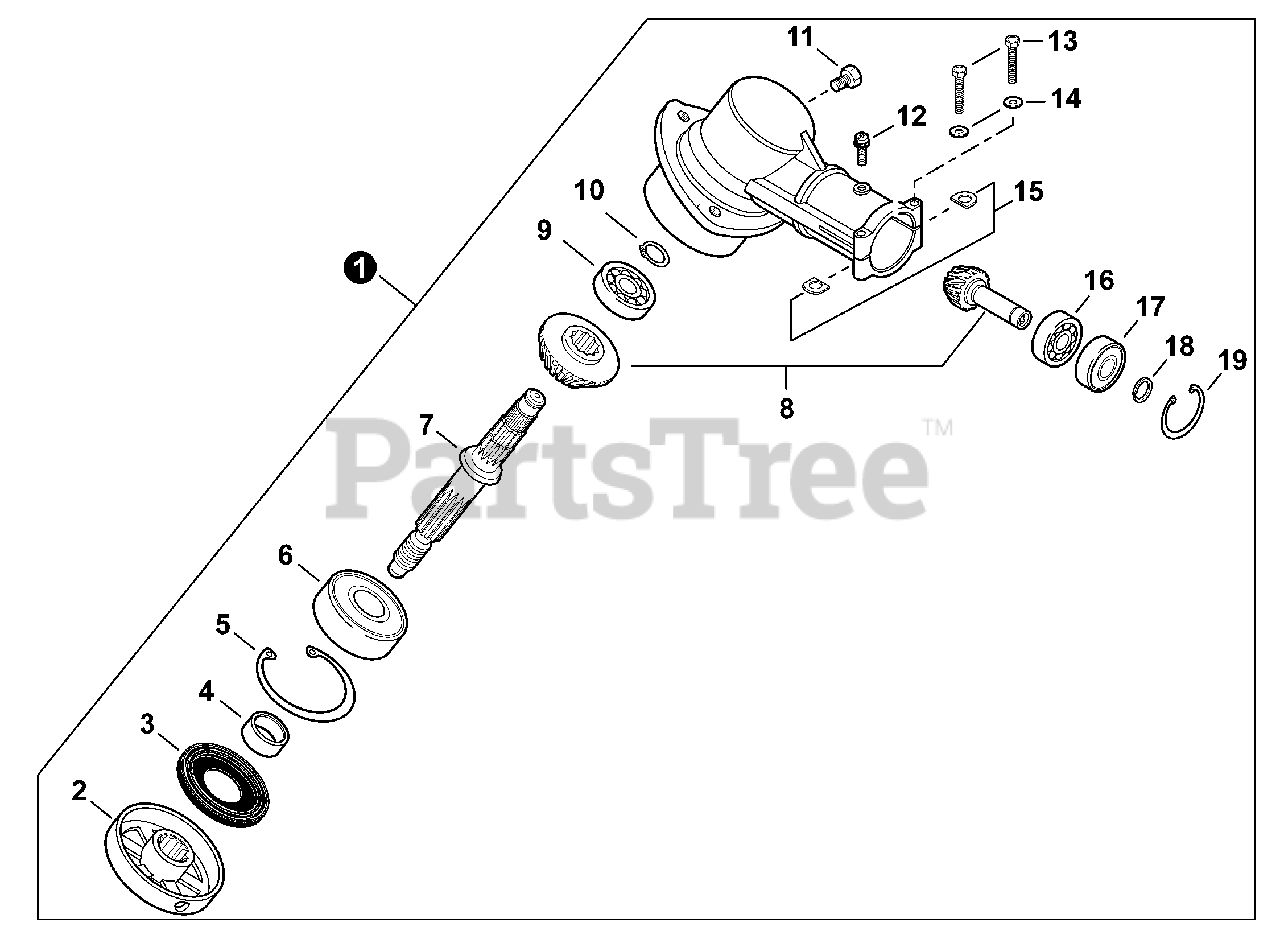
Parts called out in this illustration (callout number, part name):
1	GEAR CASE ASSY
2	PLATE, ADAPTOR - UPPER
3	SEAL, OIL 22
4	SPACER 11.8×15×9
5	RING, SNAP Ø32
6	BEARING, BALL 6201
7	SHAFT, GEAR
8	GEAR SET
9	BEARING, BALL 609
10	RING, SNAP Ø12
11	BOLT M8×8
12	SCREW 5 X 10
13	BOLT 5×35 SP
14	WASHER, FLAT 5.5×10×0.8
16	BEARING, BALL 6900
17	BEARING, BALL 6900Z
18	RING, SNAP Ø10
19	RING, SNAP Ø22
